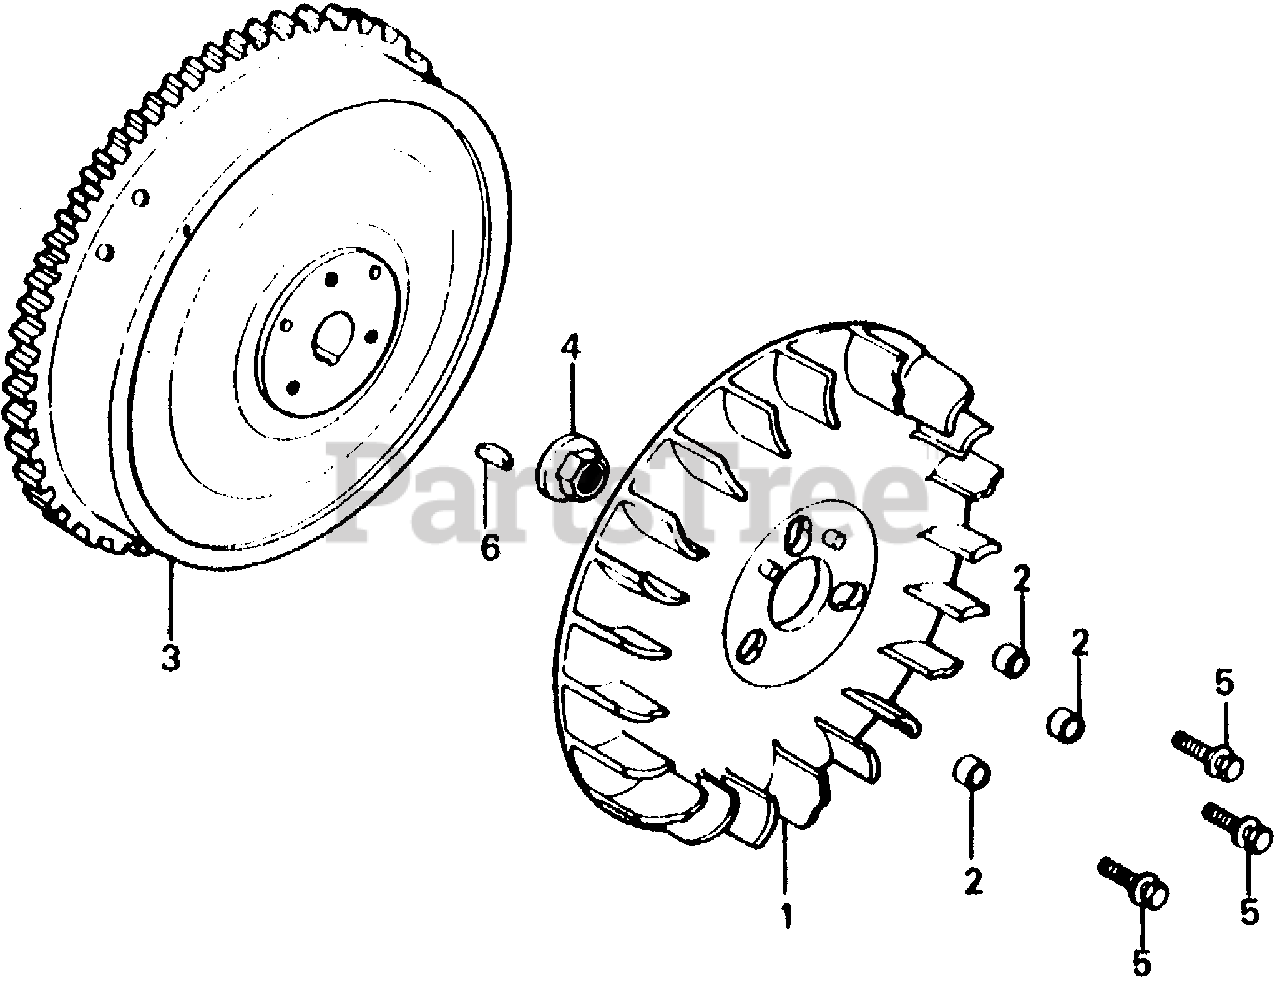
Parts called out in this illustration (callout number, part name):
1	FAN, COOLING
2	COLLAR, FAN
3	FLYWHEEL (C.D.I.)
4	NUT, SPECIAL (16MM)
5	BOLT-WASHER (6X16)
6	KEY, SPECIAL WOODRUFF (25X18)
